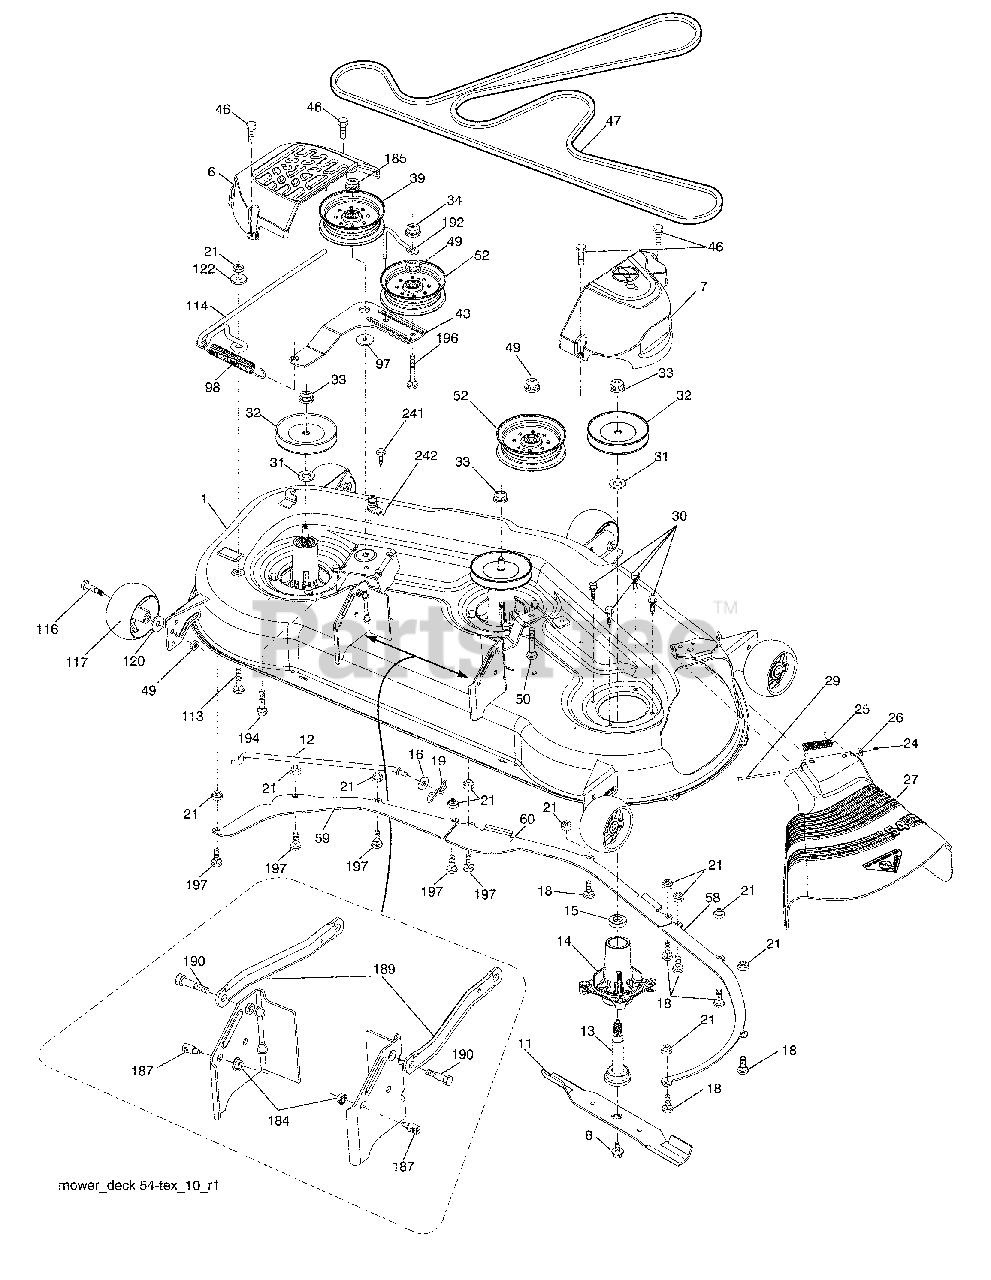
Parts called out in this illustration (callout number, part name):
1	Deck Weldment Mower
6	Cover Mandrel LH
7	Cover Mandrel RH
8	Bolt/Washer Asm. 7/16-20 unf
11	Blade Bagging
12	Bar Anti-Sway
13	Shaft Asm. w/Lower Bearing
14	Housing, Mandrel
15	Bearing, Ball, Mandrel
16	Washer 13/32 x 13/16 x 12 Ga.
18	Bolt Carr. 5/16-18 x 5/8
19	Pin Cotter 5/16 Bow tie Lock
21	Nut, Crownlock 5/16-18 unc
24	Cap Sleeve
25	Spring, Torsion
27	Deflector Shield
29	Rod, Hinge
30	Screw, Thdroll Washer Head
31	Washer, Spacer Mower Vented
32	Pulley, Mandrel
33	Nut, Flg. Top Lock
34	Nut Crownlock 3/8-16 unc
39	Pulley, Idler, Stationary
43	Arm, Idler
46	Screw, Thdroll. 1/4-20 x 5/8
47	V-Belt, Mower
49	Nut, Lock Flg. 3/8-16 unc
50	Bolt Rdhd Sqnk 3/8-16 unc x 2
52	Pulley Idler 4.50
58	Baffle Right
59	Baffle Left
60	Baffle Center
97	Washer Hardened
98	Spring Drive
113	Bolt Rdhd Sqnk 5/16-18 x 3/4
114	Rod Tension Relief
116	Bolt, Shoulder
117	Gauge Wheel
120	Washer 13/32 x 1-1/4 x 12 Ga.
122	Bushing Tension Relief
184	Nut Lock Hex Flange 5/16-18
185	Nut Lock Flange 7/16-14 Gr. 5
187	Stud Fastener w/"D" Anti-Rotation
189	Arm Susp. Mower Rear
190	Bolt Shoulder
192	Keeper Belt Idler
194	Bolt Carr Sqnk 3/8-16 x 2-1/4
196	Bolt Rdhd 3/8-16 unc x 2-3/4 Gr. 5
197	Bolt RDHD SQNK 5/16-18 unc x 1
242	Washout Port
